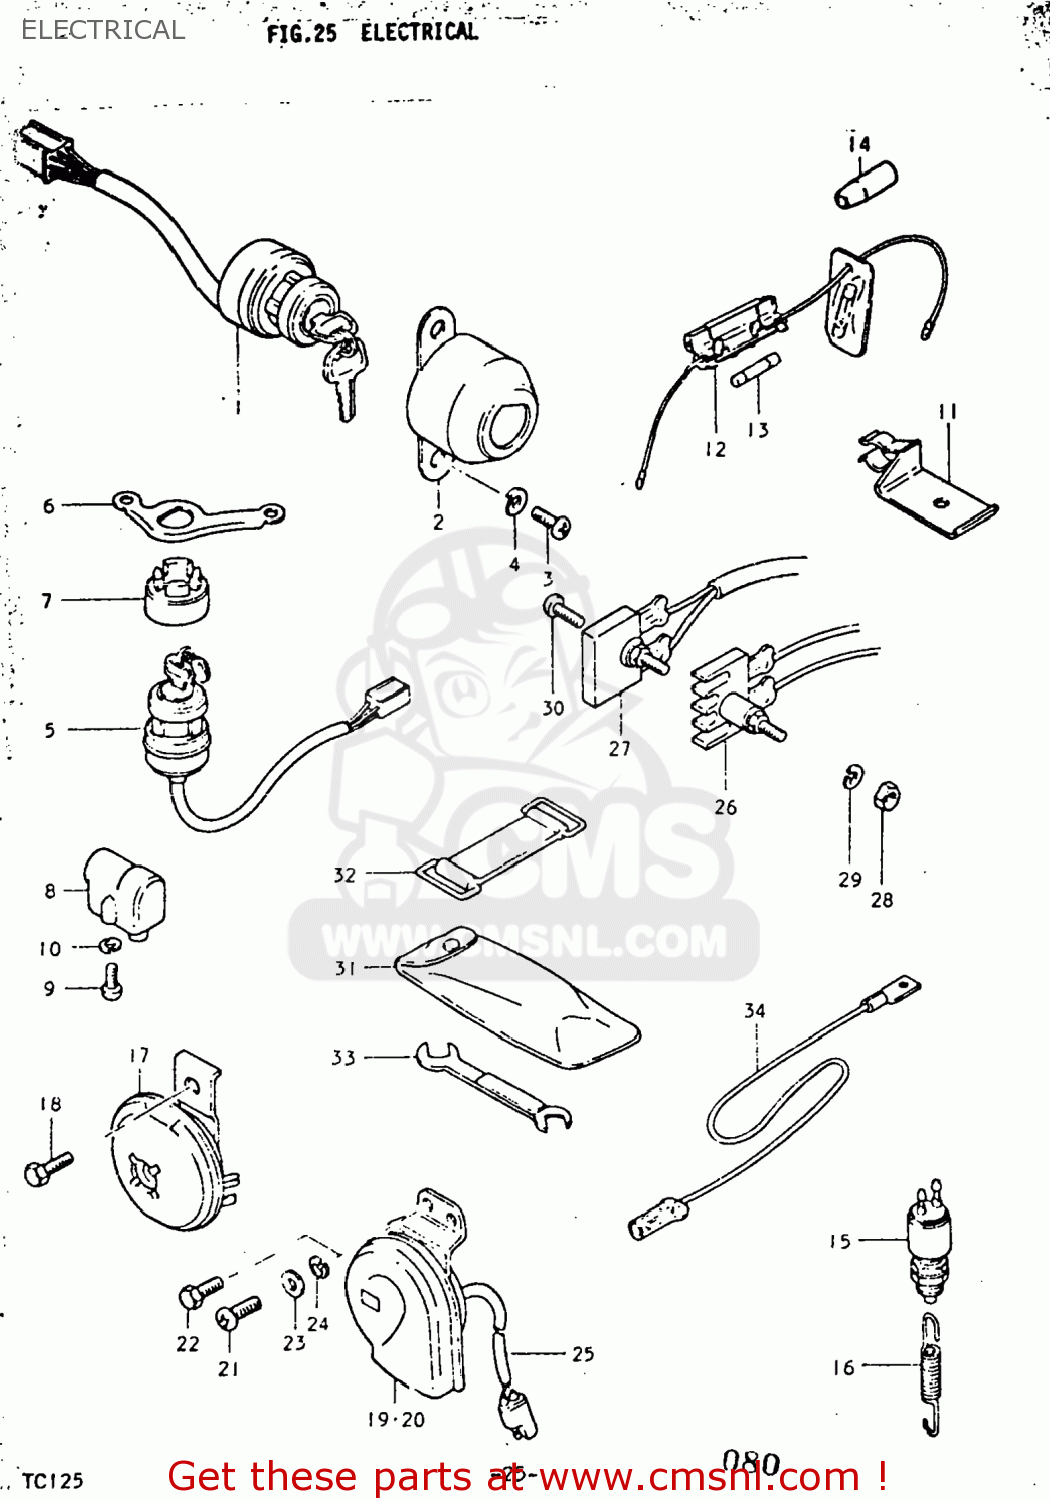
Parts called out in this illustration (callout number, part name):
1	SWITCH ASSEMBLY,IGNITION
2	BRACKET,IGNITION SWITCH
3	SCREW 6X12
4	LOCK WASHER
5	SWITCH ASSEMBLY,IGNITION
6	BRACKET,IGNITION SWITCH
7	IGN SWITCH COVE
8	LOCK ASSY,STEERING
9	Screw
10	LOCK WASHER
11	HOLDER,FUSE CASE
12	BOX ASSEMBLY,FUSE
13	FUSE(15A)
14	SEAL,DUST(10X17X45)
15	SWITCH ASSY,BRAKE LAMP
16	SPRING
17	HORN ASSEMBLY
18	BOLT
19	HORN ASSEMBLY
20	HORN ASSY
21	SCREW 6X12
22	BOLT
23	WASHER
24	LOCK WASHER
25	WIRE
26	RECTIFIER ASSEMBLY
27	RECTIFIER ASSEMBLY
28	NUT
29	LOCK WASHER
30	SCREW 5X20
31	TOOL SET
32	BAND
33	WRENCH, CONTACT POINT
34	WIRE,WIRING HARNESS LEAD
